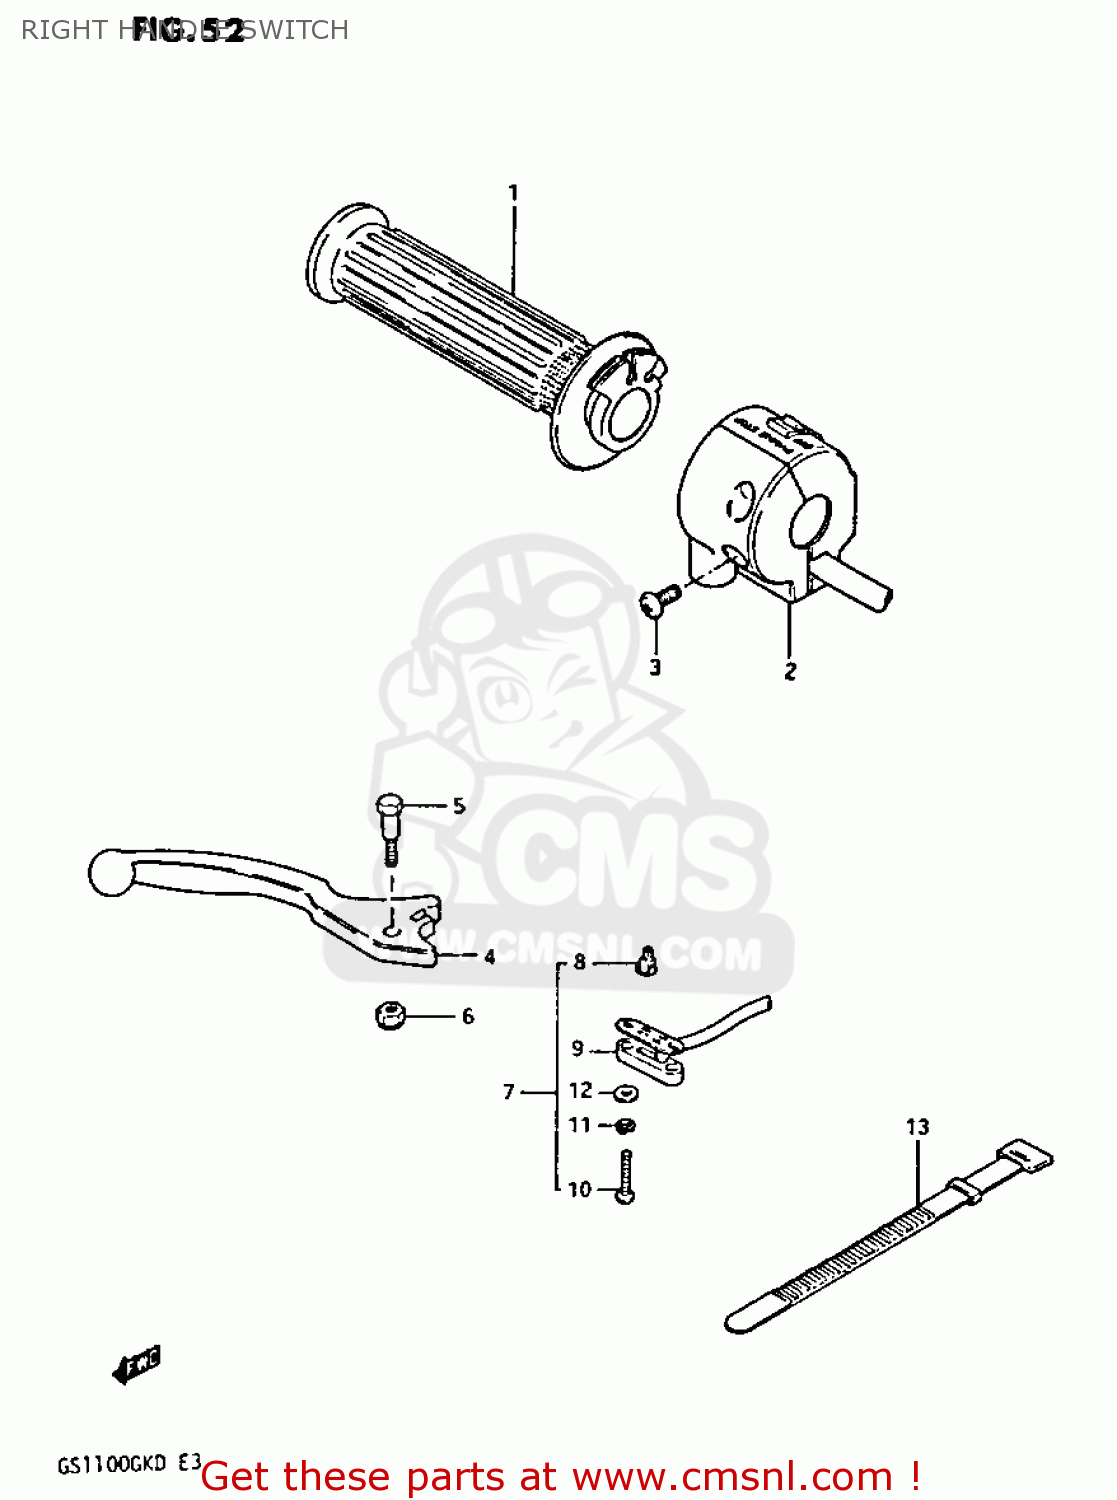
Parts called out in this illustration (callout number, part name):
1	GRIP,THROTTLE
2	SWITCH ASSEMBLY,HANDLE,RIGHT
3	SCREW
4	LEVER,BRAKE
5	BOLT
6	NUT 6MM
7	SWITCH ASSEMBLY
8	CONTACT,SWITCH
9	COVER,FR BK TERMINAL BASE
10	SCREW
11	WASHER,LOCK
12	WASHER
13	CLAMP(L:120)
